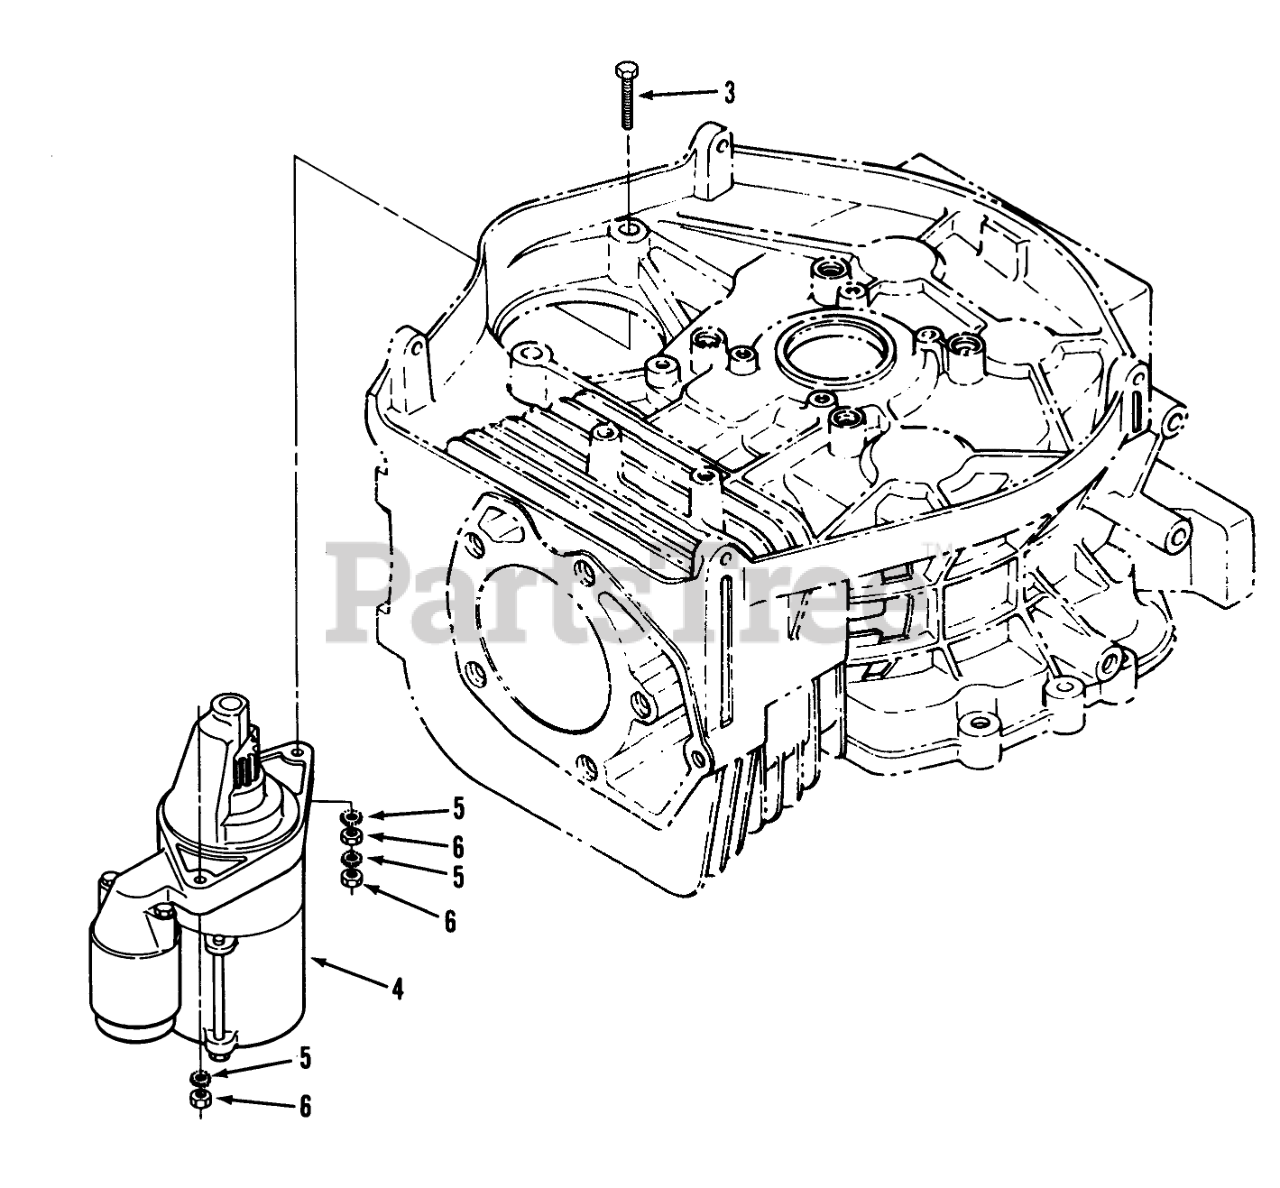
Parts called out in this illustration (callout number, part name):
1	Screw
2	STARTER
3	WASHER
4	Nut
